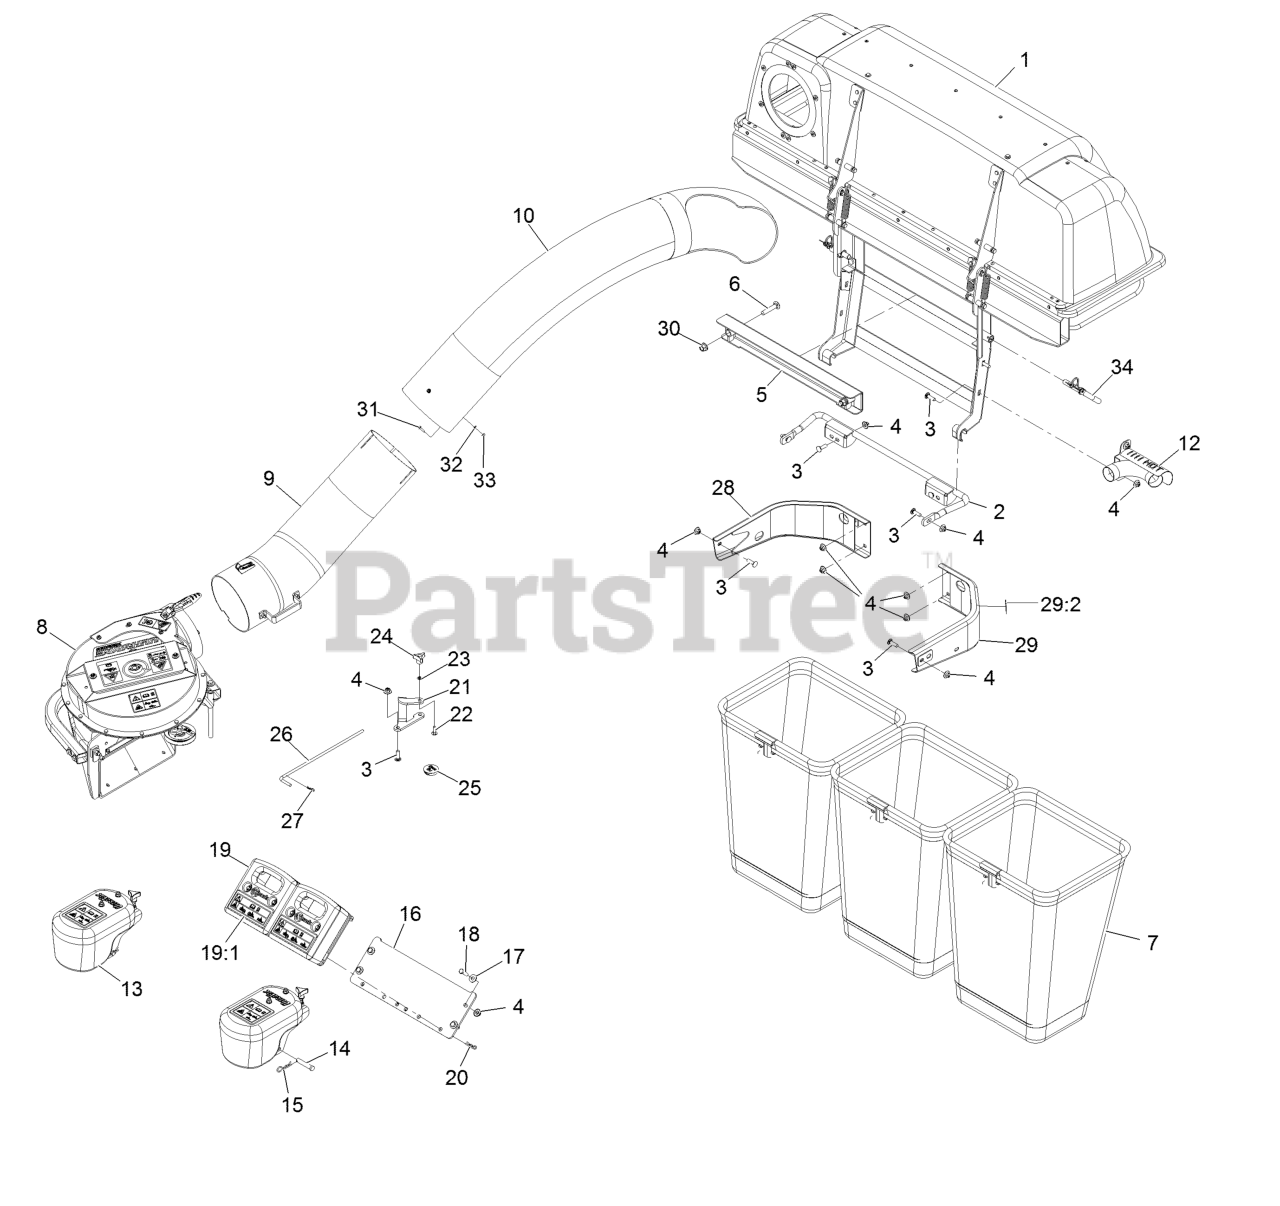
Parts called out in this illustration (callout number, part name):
1	ASM,Hood Uv 3 Bag
2	Mount-Bagger, Lower
3	Bolt-Carriage 3/8-16 X 1 1/4
4	Nut-Nyloc 3/8-16 Flg
5	Mount-Bagger, Upper
6	Bolt-Carriage 1/2-13 X 2 1/2
7	Bag And Frame ASM
8	ASM, Blower Large - Svc Only
9	Lower Tube ASM
10	Tube-Upper
12	Exhaust Diverter ASM
13	ASM,Caster Weight
14	Pin-Clevis
15	Hairpin-Cotter
16	Plate, Weight Mounting
17	Washer-3/8 Std
18	Screw-HH 3/8-16 X 1 1/4
19	Asm, Weight (103-6364-01) W/Decals
19:1	Decal-Warning Weight
20	Hairpin-Cotter
21	Bracket,Belt Cover
22	Bolt-Carriage 5/16-18 X 1
23	Ring-Bolt Retaining
24	Knob-3 Prong
26	Pin, Chute Pivot
27	Hairpin-Cotter
28	Bumper-RH
29	LH Bumper ASM
29:2	Decal-Warning
30	Nut-Lock 1/2-13
31	Screw-HWH #10-24 X 3/4
32	Washer-#10 Std
33	Nut-Nyloc #10-24
34	Pin-Mount, Bagger
